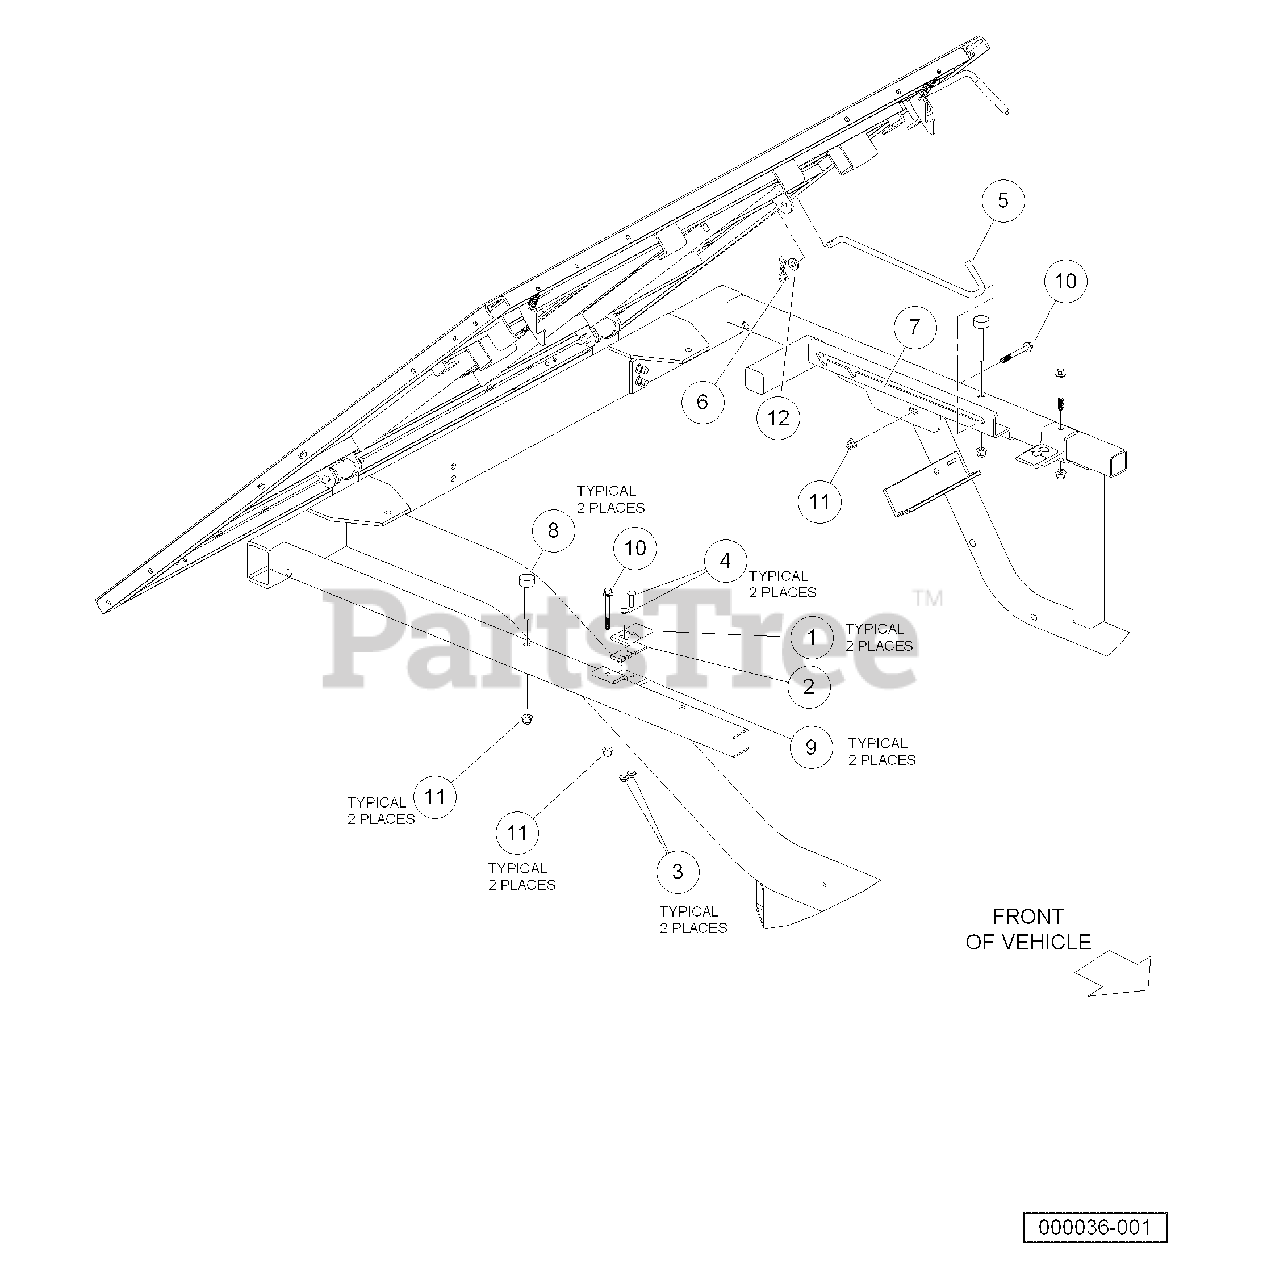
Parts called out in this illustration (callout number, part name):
1	Latch Plate, Tilt Bed
2	Latch Plate Shim
3	Locknut, 1/4-20 Hex Whiz
4	Bolt, Carriage, 1/4-20 X 1.0
6	Pin, Bow Tie Locking
7	Track, Prop Rod
8	Bumper, Bed, Mtg, Front
9	Bracket, Latch, Bed
10	Bolt Flanged Head, M8 X 1.25 X 65
11	Lock Nut, Flg M8 X 1.25 Nylon
12	Washer, 3/8 Type A Flat
